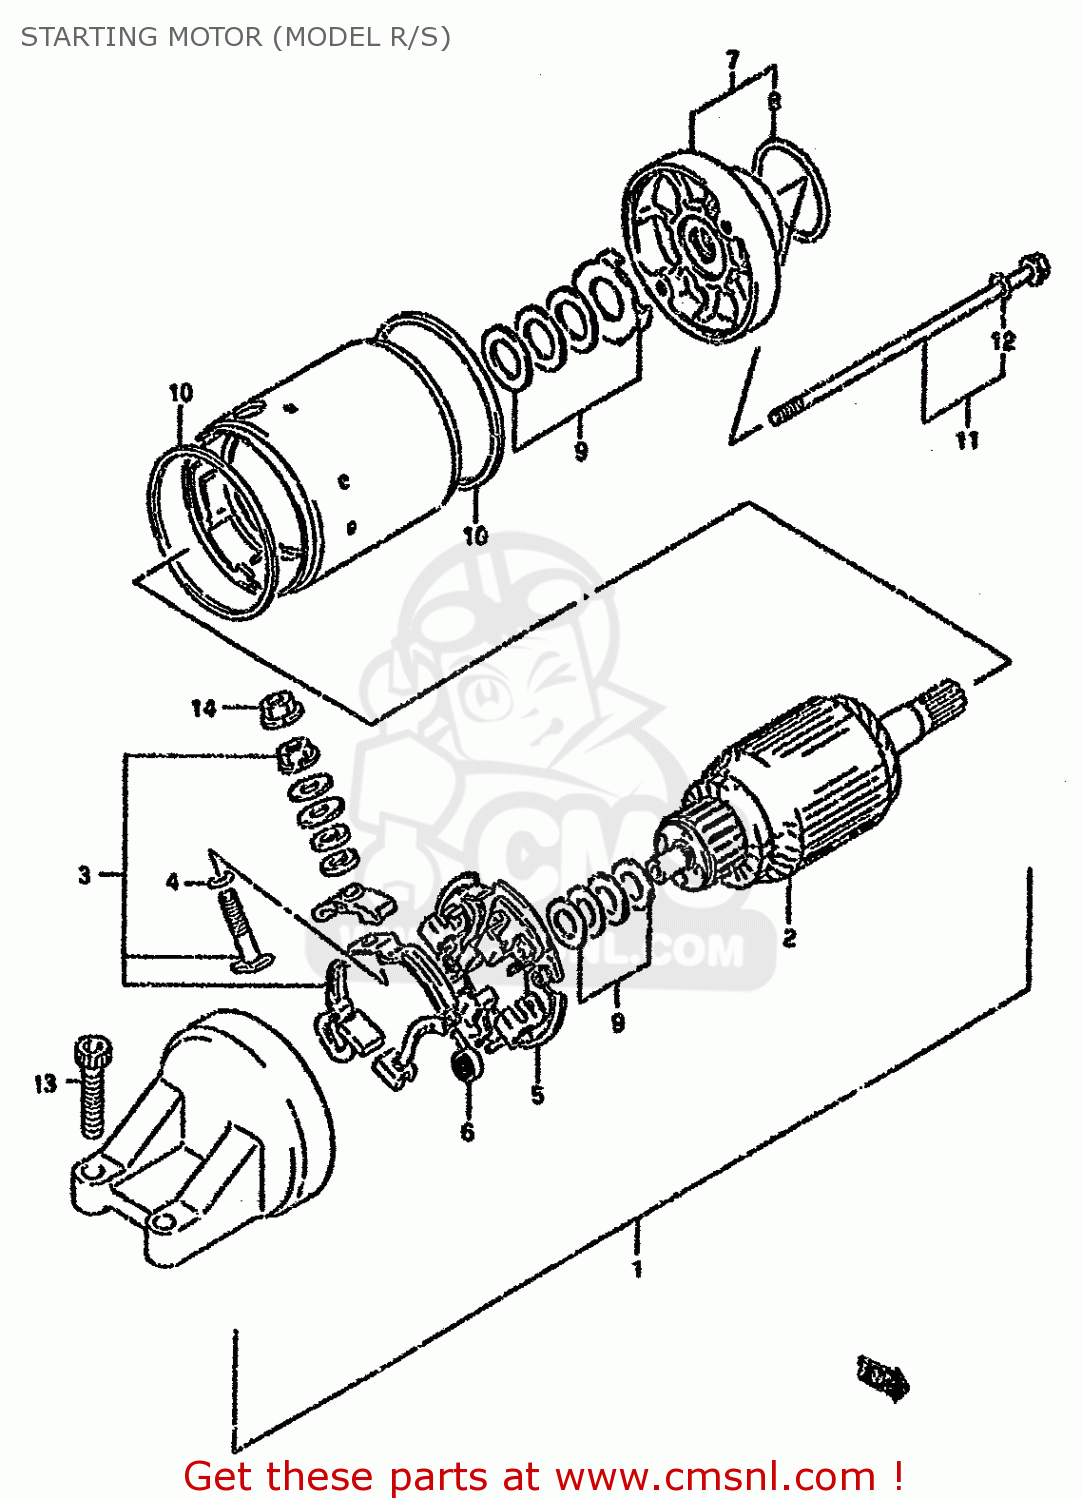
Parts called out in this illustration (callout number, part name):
1	MOTOR ASSEMBLY,STARTING
2	ARMATURE
3	TERMINAL SET,BRUSH,PLUS
4	O RING
5	BRUSH,HOLDER SET
6	SPRING,BRUSH
7	BRACKET ASSEMBLY,FRONT
8	O-RING
9	SHIM SET,STARTING MOTOR
10	O RING
11	BOLT SET,STARTING MOTOR
12	O RING
13	BOLT,OIL PAN
14	NUT
16	BOLT
17	NUT
